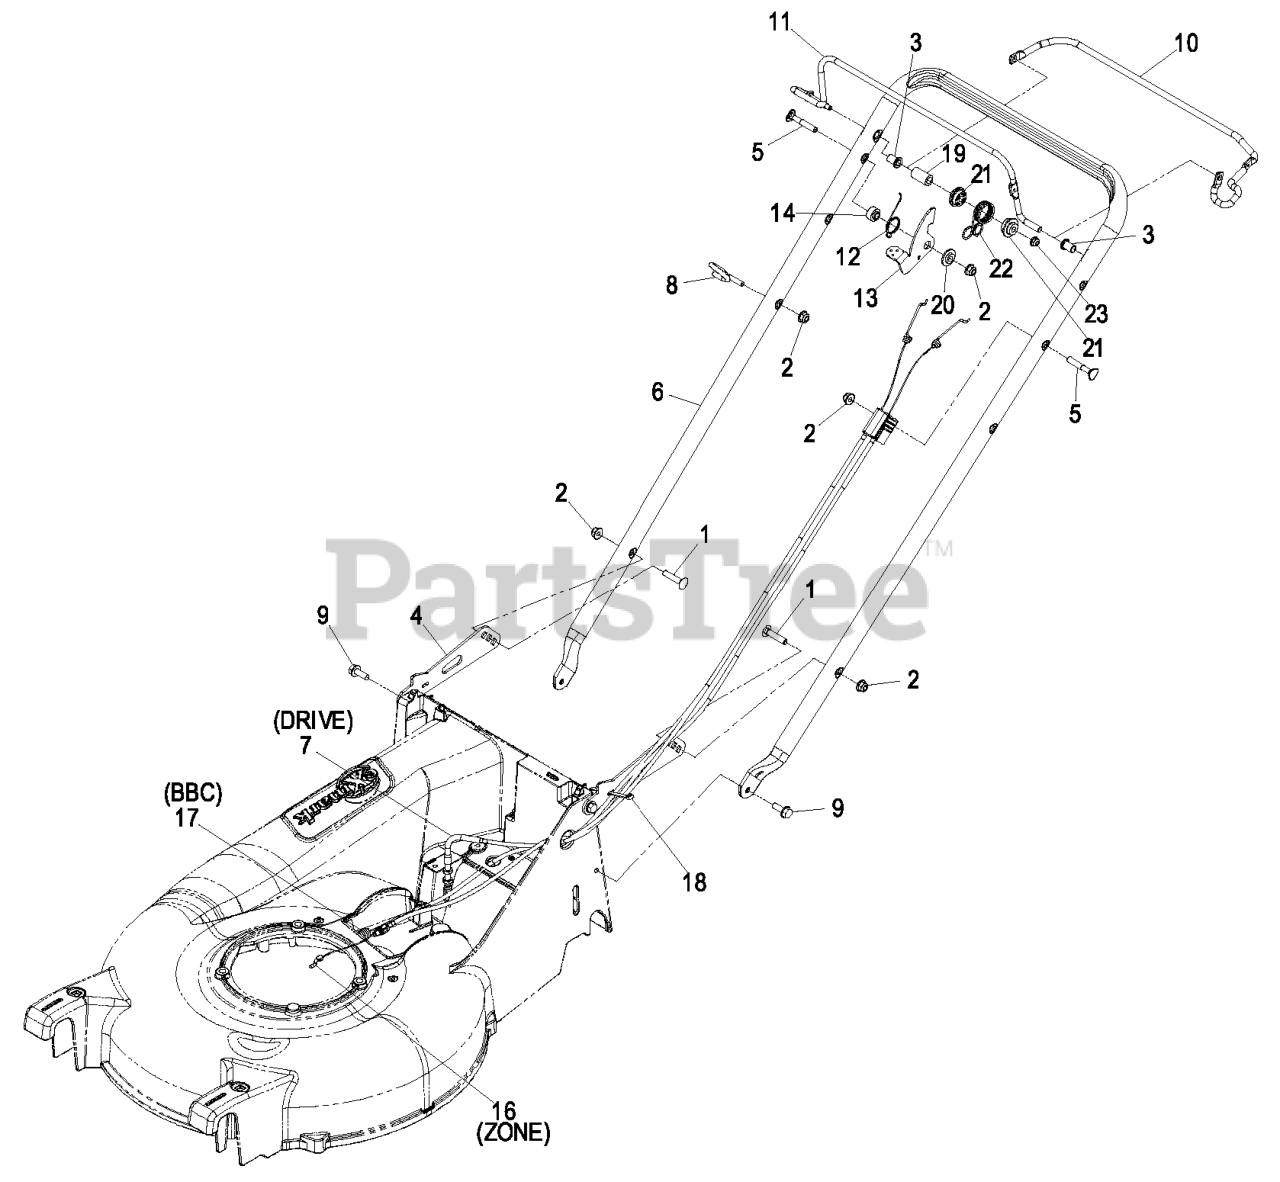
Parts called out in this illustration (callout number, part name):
1	BOLT-CARR
2	NUT-HF, NI
3	BUSHING-HANDLEBAR
4	BRACKET,HANDLEBAR
6	HANDLEBAR-P21
8	GUIDE,ROPE
9	SCREW-TAPTITE
11	BAIL
12	SPRING-LEVER, BBC
13	LEVER-BBC
14	BUSHING-STEPPED
17	CABLE-BBC
18	TIE-CABLE
19	SPACER
20	WASHER-STEPPED
21	BUSHING-SPRING, PIVOT
22	KIT-BBC RETURN
